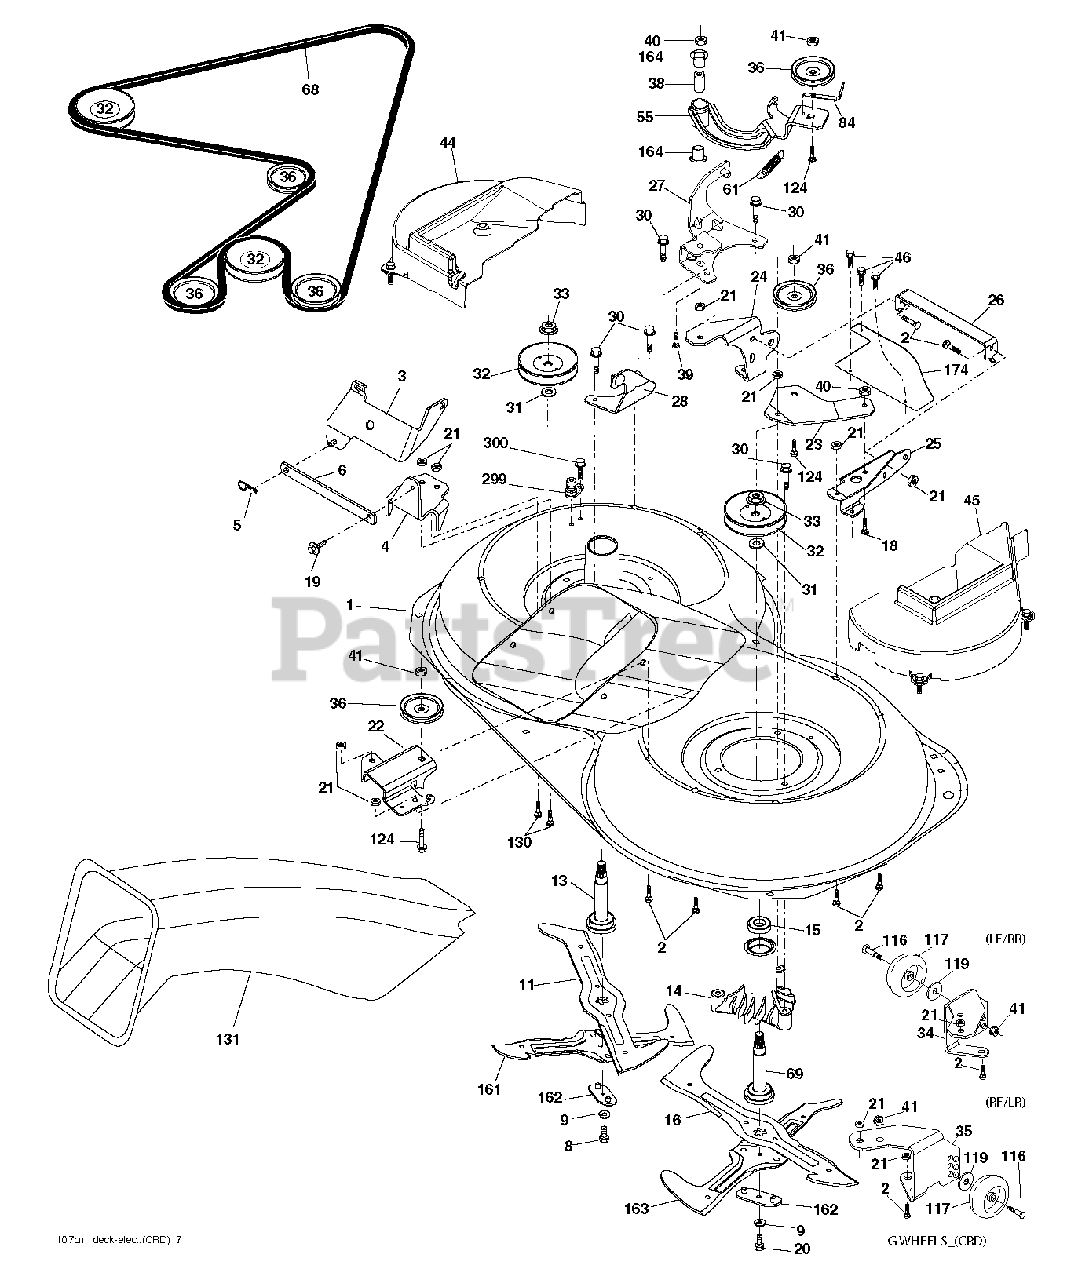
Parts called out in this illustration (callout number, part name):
2	BOLT
3	BRACKET.ASM.BAR.SWAY.CHASS
5	RETAINER-SPRNG RB
6	BAR SWAY
9	LOCKWASHER
11	BLADE.3N1.LH.CRD
13	SHAFT ASM VENT
14	HSG MANDREL
16	BLADE.3N1.RH.CRD
19	BOLT SHD 5/16-18
21	LOCKNUT
22	BRACKET
23	BRACKET
27	BRACKET
30	SCREW, WASHER HEAD
31	WASHER.SPACER.MANDREL
33	NUT.FLANGE.LOCK.TOP
36	PULLEY.IDLER.4.25
40	LOCKNUT
41	NUT LOCK FLG 3/8-16 UNC
46	SCREW.1/4-20X5/8
55	ARM IDLER
68	HEX-BELT 107 MOWER
69	SHAFT.ASM.W/LWR.BRG.RH.THREAD
84	KEEPER, BELT IDLER
116	BOLT.SHOULDER.3/8-16X3-5/8
117	WHEEL. GUAGE RALLY
124	BOLT.3/8-16X1.50
131	CHUTE BAGGER
164	BRNG T
299	PORT.WASHOUT
